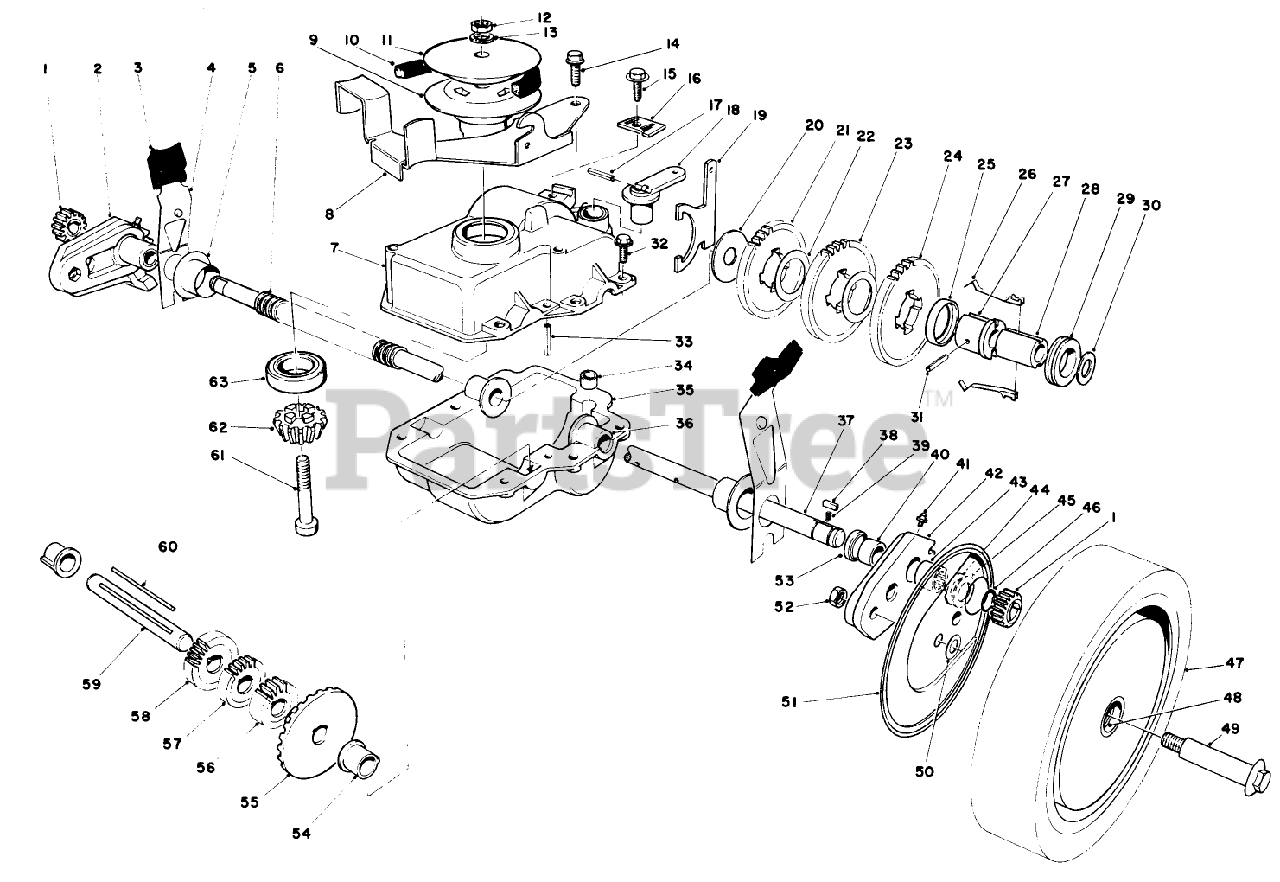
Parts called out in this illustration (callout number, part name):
1	GEAR-PINION
2	PIVOT ARM ASM RH
3	KNOB-ARM
4	SPRING ARM ASM SP
5	CAP-END
6	CONDUIT-CONVOLUTED, SPLIT
9	PULLEY-LOWER HALF
10	V-BELT
12	NUT-LOCK, NI
13	WASHER-FLAT
14	SCREW
15	SCREW-THD ROLL, HWH
17	PIN-SPRING
18	LEVER-SHIFT
20	WASHER
21	Gear-38T
22	WASHER
23	GEAR-42T
26	KEY-SHIFT
28	SLEEVE
29	COLLAR-SHIFT
30	WASHER-PLAIN
32	SCREW-HWHTF
33	ROLL PIN 3/16 X 1 IN
34	BUSHING-YOKE
38	KEY RECTANGULAR
39	SPRING-COMPRESSION
40	BUSHING
41	FITTING-GREASE
45	WASHER-THRUST, OUTER
46	RING-RETAINING
47	WHEEL-TIRE ASM SERVICE
48	BUSHING
49	WHEEL BOLT
50	WASHER
51	WHEEL COVER
52	NUT-LOCK
54	BUSHING
56	GEAR-12T
57	GEAR-14T
58	GEAR-18T
63	BEARING-BALL
